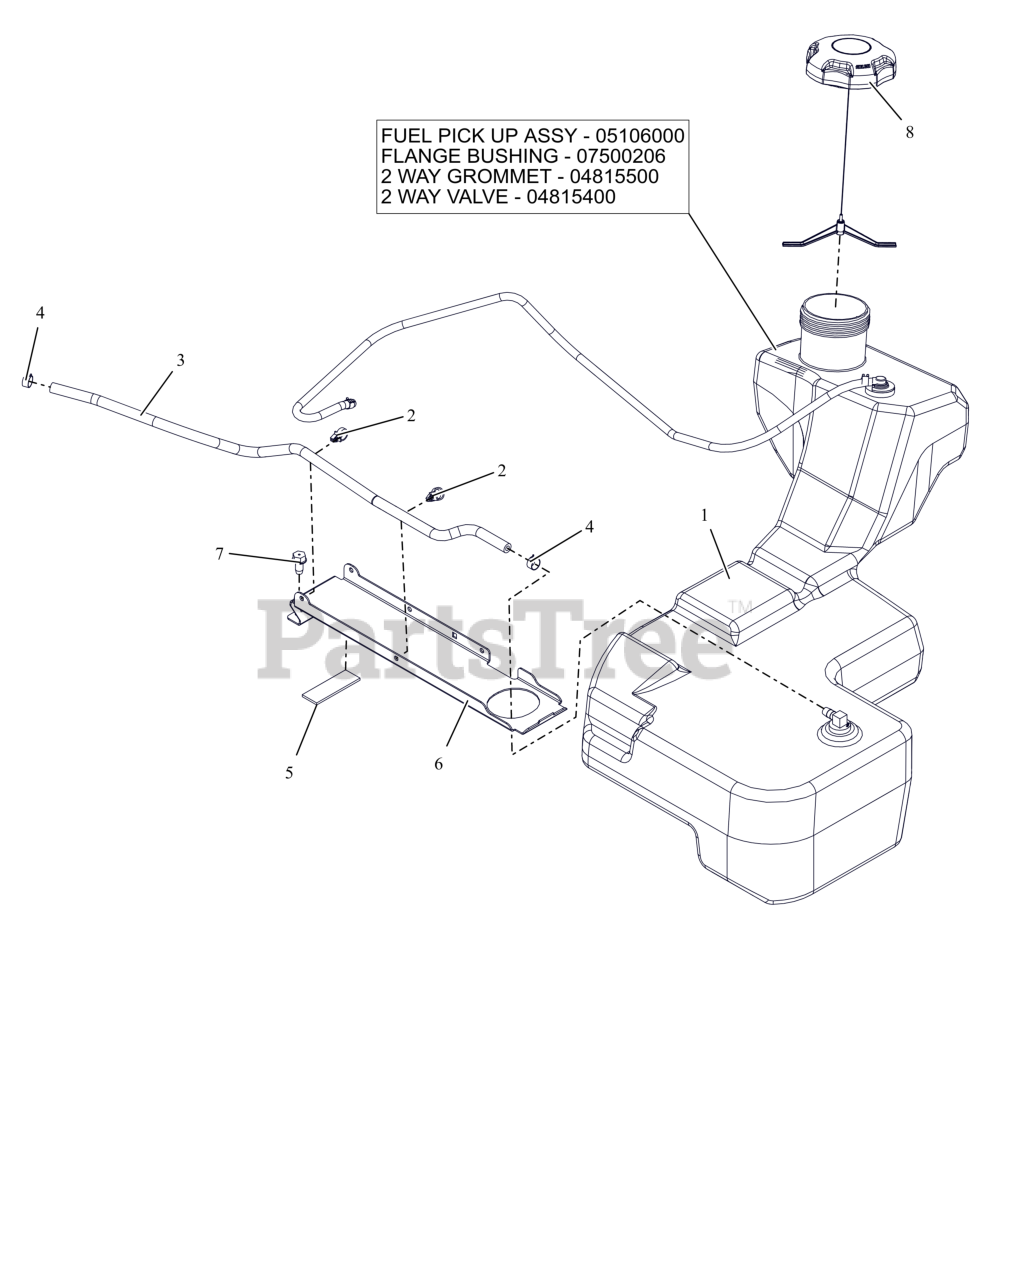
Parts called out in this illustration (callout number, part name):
1	ASM, FUEL TANK-HD
1	ASM, HD FUEL PICK-UP
1	BSHG-FLG .375X1.062X.625 NITR
1	GROMMET, 2-WAY
1	VALVE, 2-WAY
2	ROUTING CLIP (1/2" ID)
3	HOSE, .25 LOW-PERM BULK GAS
4	CLAMP, FUEL LINE
5	PAD,RBR 1.0"X3.0" W/ADHESIVE
6	BRKT, FUEL TANK HOLD DOWN
7	SCR,TAP .375-16X.75 HWH TR ZCC
8	CAP, FUEL - 3.50 RATCHET INLET VENT
